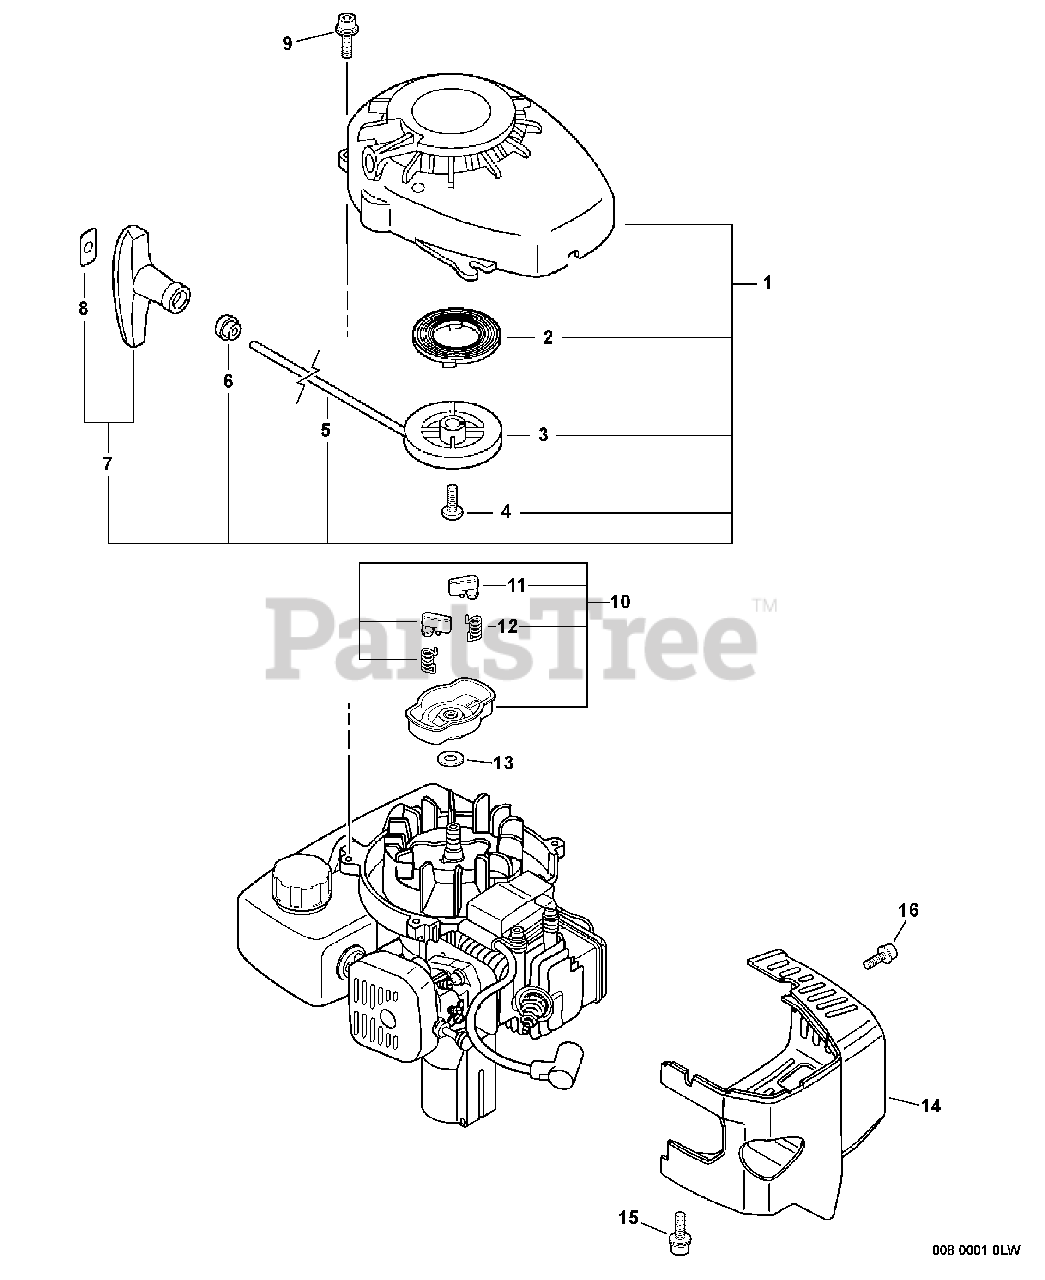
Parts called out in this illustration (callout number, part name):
1	STARTER ASSY
2	SPRING, REWIND
3	REEL, ROPE
5	ROPE, STARTER - 3X890
6	GUIDE, ROPE
7	GRIP, STARTER
8	RETAINER, ROPE
9	SCREW - 4X16
10	STARTER PAWL ASSY
11	PAWL, STARTER - BLACK
12	SPRING, RETURN
13	LOCKWASHER - 8
14	COVER, ENGINE
15	SCREW - 4X18
16	SCREW - 4X8
